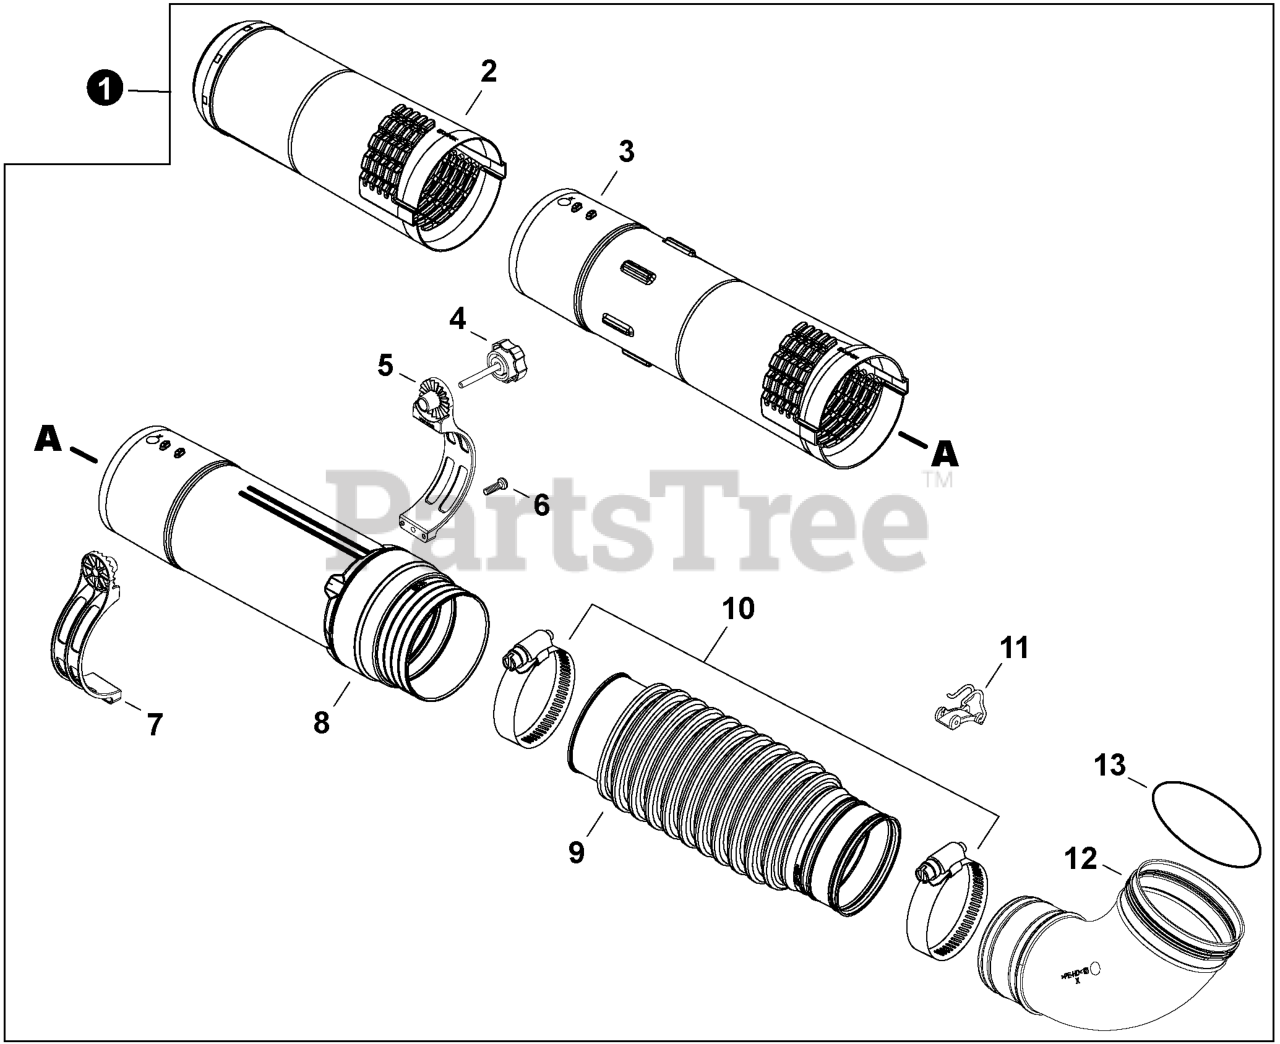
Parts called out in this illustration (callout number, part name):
1	TUBE KIT, BLOWER, TUBE MOUNT
2	TUBE, BLOWER - NOZZLE
3	TUBE, BLOWER - STRAIGHT
4	KNOB, SCREW
5	BRACKET, HANDLE - RIGHT
6	BOLT, TORX 5x20
7	BRACKET, HANDLE - LEFT
8	TUBE, BLOWER - SWIVEL
9	TUBE, BLOWER - FLEXIBLE
10	CLAMP - BAND
11	CLIP, CABLE
12	TUBE, BLOWER - ELBOW
